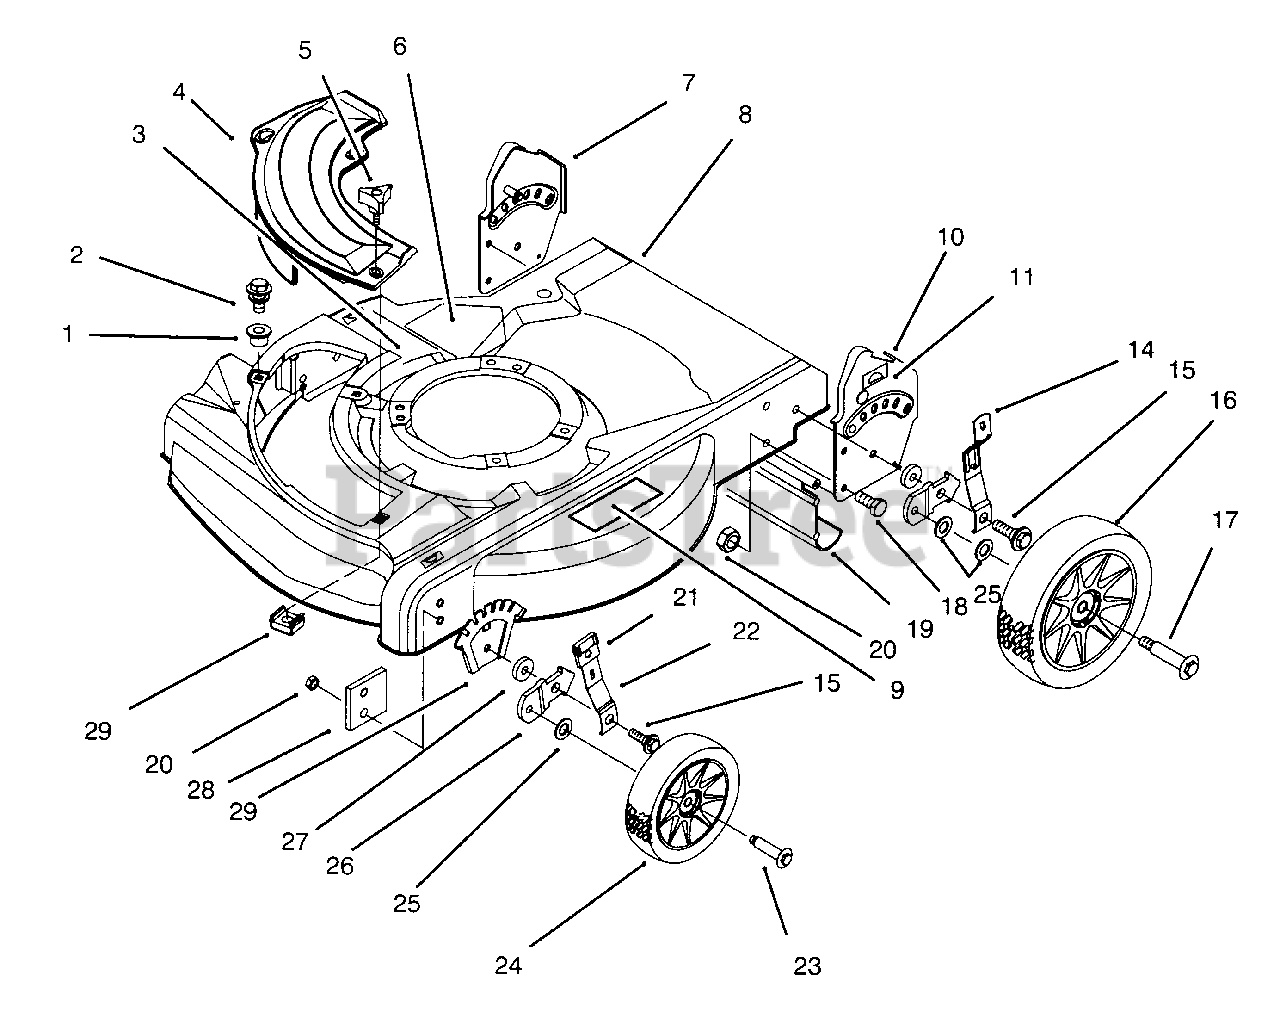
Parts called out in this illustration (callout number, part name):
1	Grommet-Plastic
2	Screw-Thread Forming
3	Decal-Danger
4	Plate-Cover, Mulch
5	Knob
6	Decal-Danger
7	Handle Bracket Ass'y-RH
8	Housing & Baffle Ass'y (Incl. Ref. #1-3, 6, & 9
9	Decal-Warning
10	Handle Bracket Ass'y-LH
11	Decal-H.O.C. L.H.
14	Spring Arm Assembly
15	Bolt-Shoulder
16	Wheel Ass'y-8"
17	Bolt-Wheel
19	Shield-Trailing
21	Knob-H.O.C. Lever
22	Arm-Spring, Front
23	Bolt-Wheel
24	Wheel Ass'y-6"
25	Washer-Wheel Bolt
26	Bracket-H.O.C.
28	Plate-Baffle
29	Plate-H.O.C. Front
30	Nut-Cage
